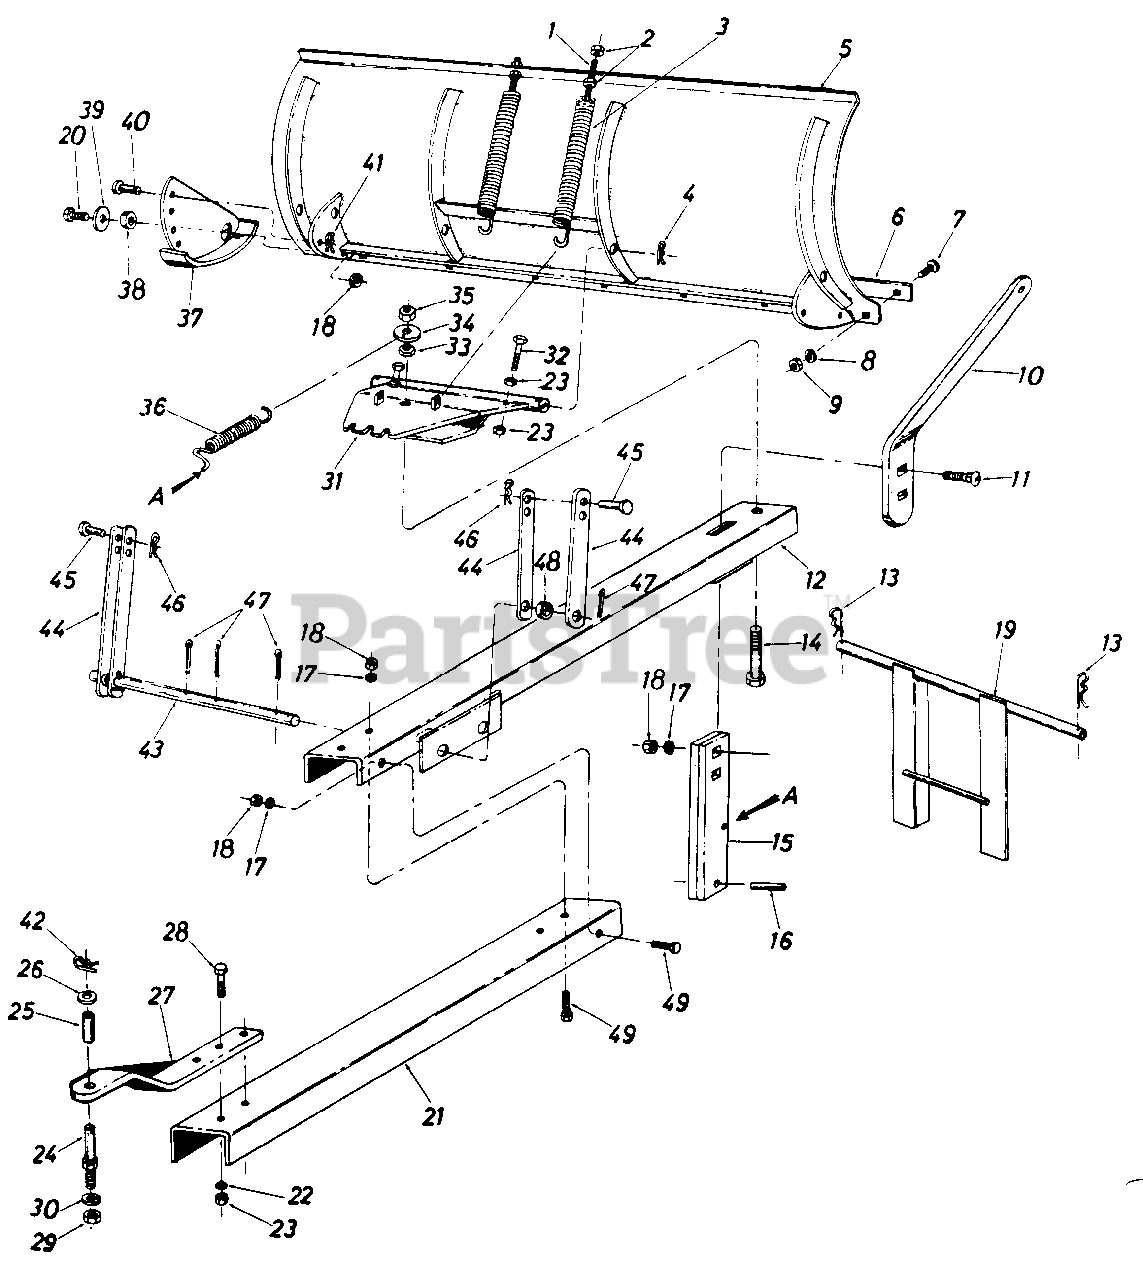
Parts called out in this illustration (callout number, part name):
1	Hex Scr. 3/8-16 x 4.50" Lg.
2	Hex Nut 3/8-16 Thd.
3	Blade Adjustment Spring
4	Hair Pin Cotter, 5/32
5	54" Blade Ass'y.
6	Wear Plate
7	Carriage Bolt 5/16-18 x .75" Lg.
8	L.-Wash. 5/16" Scr.
9	Hex Nut 5/16-18 thd.
10	Lock Extension Bar
11	Carriage Bolt 3/8-16 x 1.25" Lg.*
12	Front Push Bar Ass y.
13	Hair Pin Cotter, 5/32
14	Hex Scr. 3/4-10 x 3.50" Lg.
15	Angle- Lock Bar
16	Spring Pin Spirol .25" Dia. x 1.00" Lg.
17	L.-Wash. 3/8" Scr.
18	Hex L.-Nut 3/8-16 Thd.
19	Guide Bracket Ass'y.
20	Hex Scr. 3/8-16 x .75" Lg.
21	Rear Push Bar Channel
22	L.-Wash. 1/2" Scr.
23	Hex Nut 1/2-13 Thd.*
24	Link Clevis Pin
25	Spacer 1" O.D. x 21/32" I.D. x .75" Lg.
26	Fl-Wash. 21/32 I.D. x .090 O. D.
29	Hex Jam L.-Nut 5/8-18 Thd.
30	L.-Wash. 5/8" Scr.
31	Pivot Plate Ass'y.
32	Hex Scr. 1/2-13 x 2.00" Lg.
33	Hex Jam Nut 3/410 Thd.
34	Fl.-Wash. 3/8" ISpecial
35	Hex LockNut 3/4-1 Thd.
36	Angle Lock Spring
37	Skid Assembly
38	Bushing, Pivot Skid
39	Fl.-Wash. .385" I.D. x 1.00" O.D.
40	Clevis Pin 5/16" Dia. x 3/4" Lg.
41	Hair Pin Cotter 3/32"
42	Hair Pin Cotter, 5/32
43	Lift Shaft
44	Lift Link
45	Clevis Pin 1/2" Dia. x 1.00" Lg.
46	Hair Pin Cotter, 3/32"
47	Cotter Pin 1/8" Dia. x 1.50" Lg.
48	Spacer, Lift Link
49	Hex Scr. 3/8-16 x 1.00" Lg.
